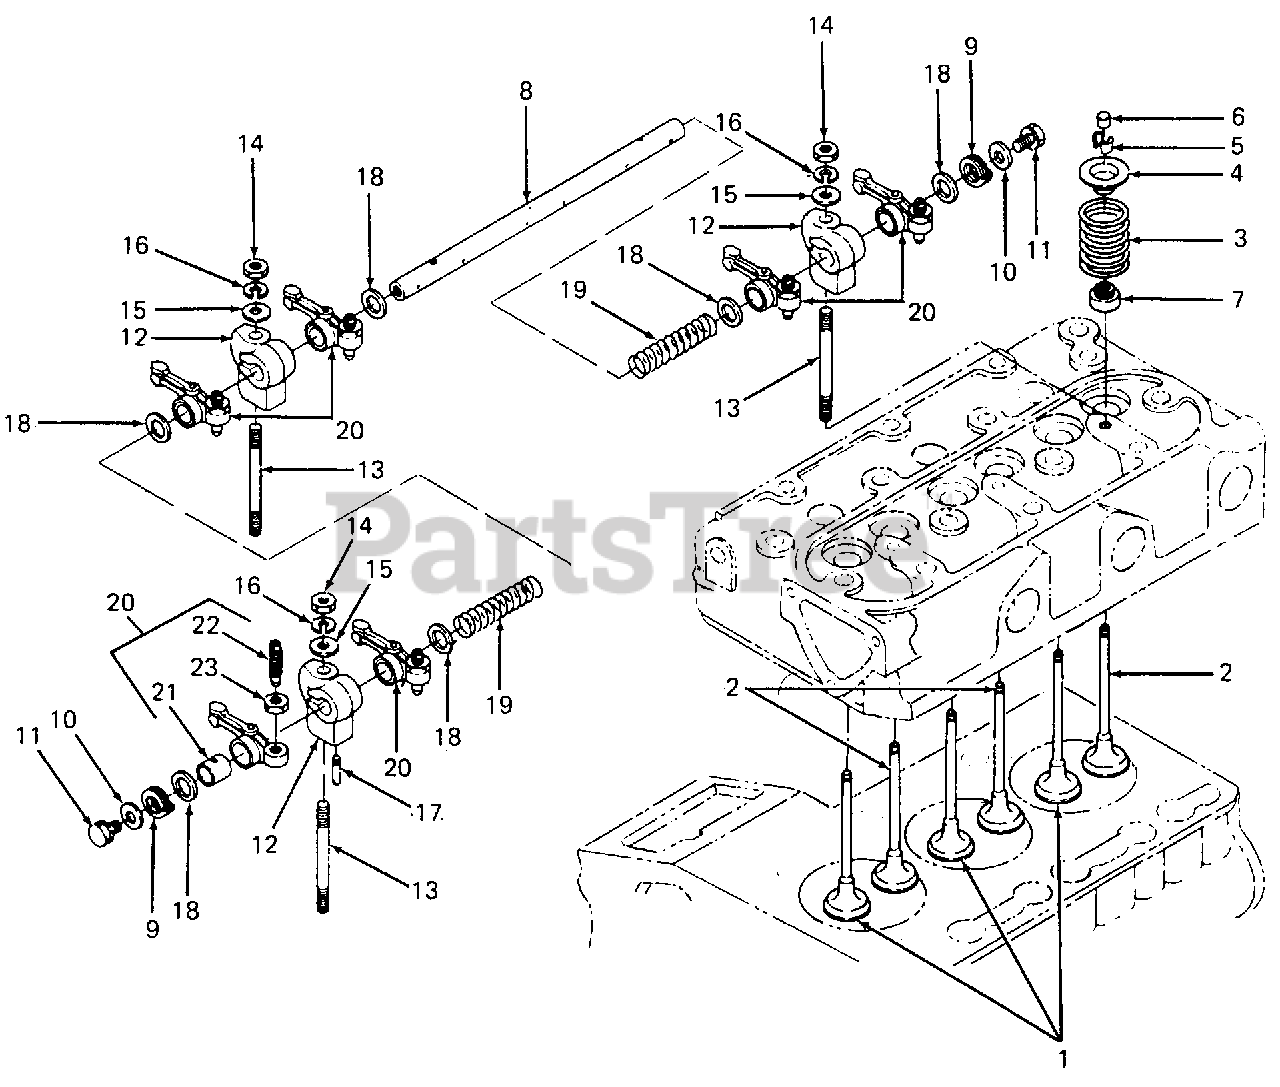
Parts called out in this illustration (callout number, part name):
2	Valve, Exhaust
3	Spring, Valve
4	Retainer, Valve Spring
5	Collar, Valve Spring
7	Seal, Valve Stem
8	Shaft, Rocker Arm
11	Screw, Hex Cap w/Washer
12	Support, Rocker Arm
16	Washer, Spring
17	Screw, Rocker Arm Shaft
18	Washer, Rocker Arm Shaft
19	Spring, Rocker Arm
20	Arm Assy, Rocker
22	Screw, Adjusting
